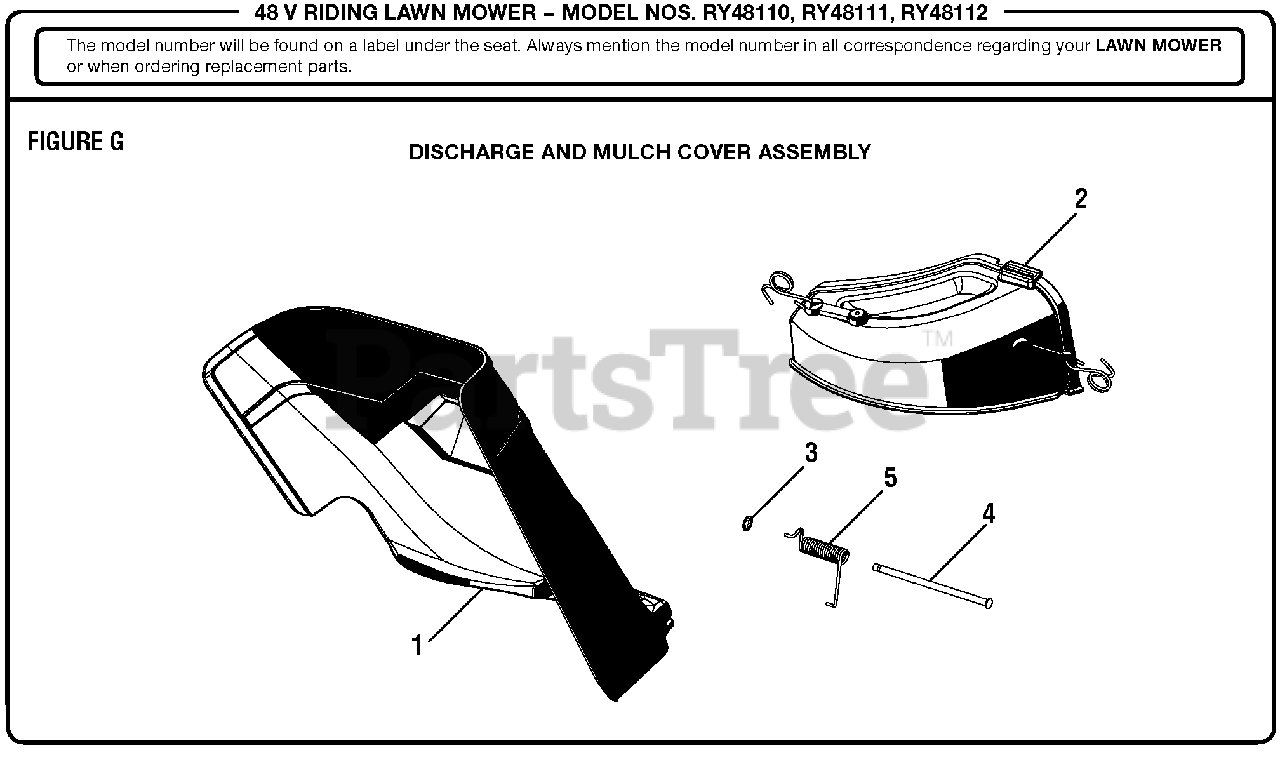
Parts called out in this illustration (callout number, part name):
1	Grass Deflector
2	Mulch Cover Kit
3	Retainer Clip
4	Hinge Pin (7.85 x 175.85)
5	Torsion Spring (19 x 62 x 3.02t)
